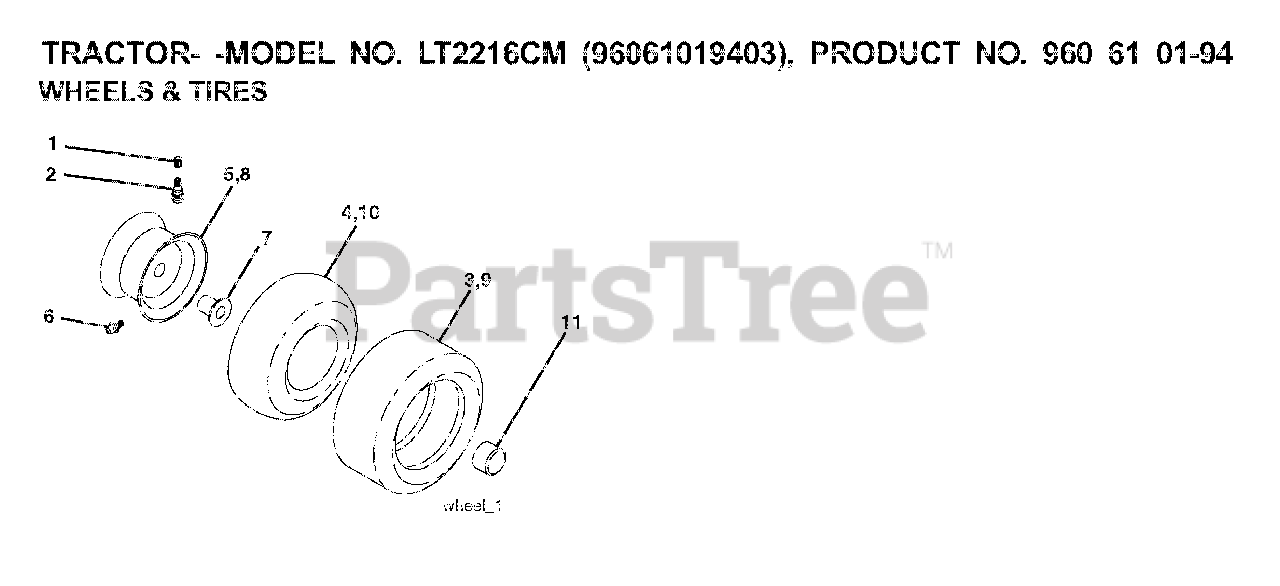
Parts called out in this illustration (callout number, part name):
1	VALVE CAP
2	VALVE STEM LT
3	TIRE HEAVY DUTY
4	TUBE.5.3/4.5/6
5	RIM ASM 6" FRONT SILVER
6	FITTING LT
7	BEARING T
8	RIM ASM 8" REAR SILVER
9	TIRE HEAVY DUTY
10	TUBE
11	CAP, AXLE BLK
